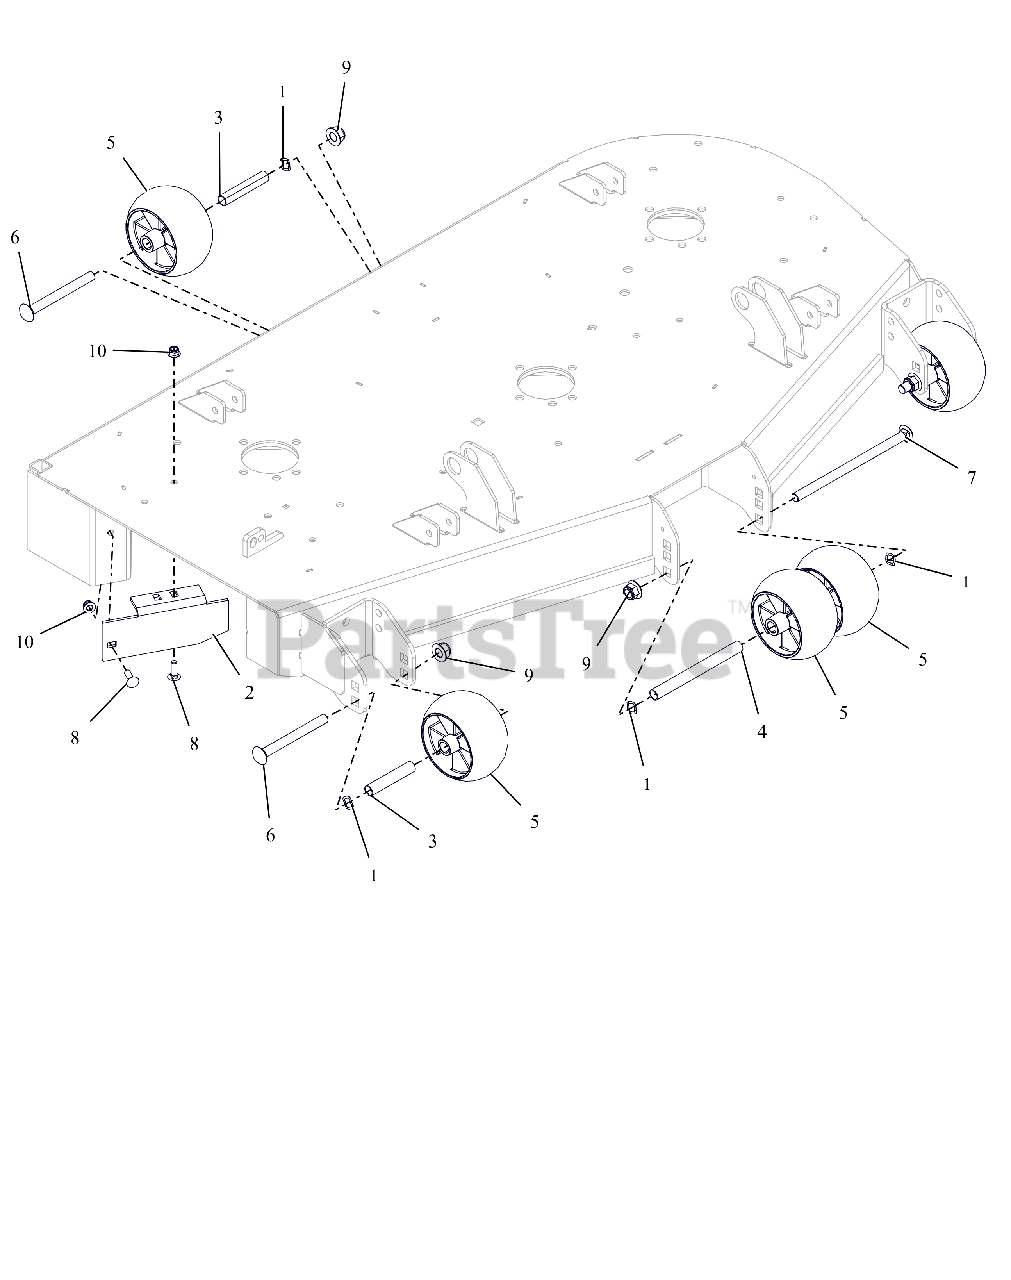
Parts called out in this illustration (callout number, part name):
1	WAVE WASHER .531X.781X.125FH
2	BAFFLE, 44/48" SIDE DISCHARGE
3	SPACER, .510X.625X3.35
4	SPACER, .510X.625X6.50
5	ANTI-SCALP WHEEL - 5X3 CTR
6	BLT-RDHDSQNK .50-13X5.00 GR5YZ
7	@BLT-RDHDSQNK .50-13X8.50 G5YZ
8	@BLT-RDHDSQNK .31-18X1.00 G5YZ
9	@NUT-LK-NYL-FLG .50-13 YWZC
10	@NUT-LK-NYL-FLG .31-18 YWZC
